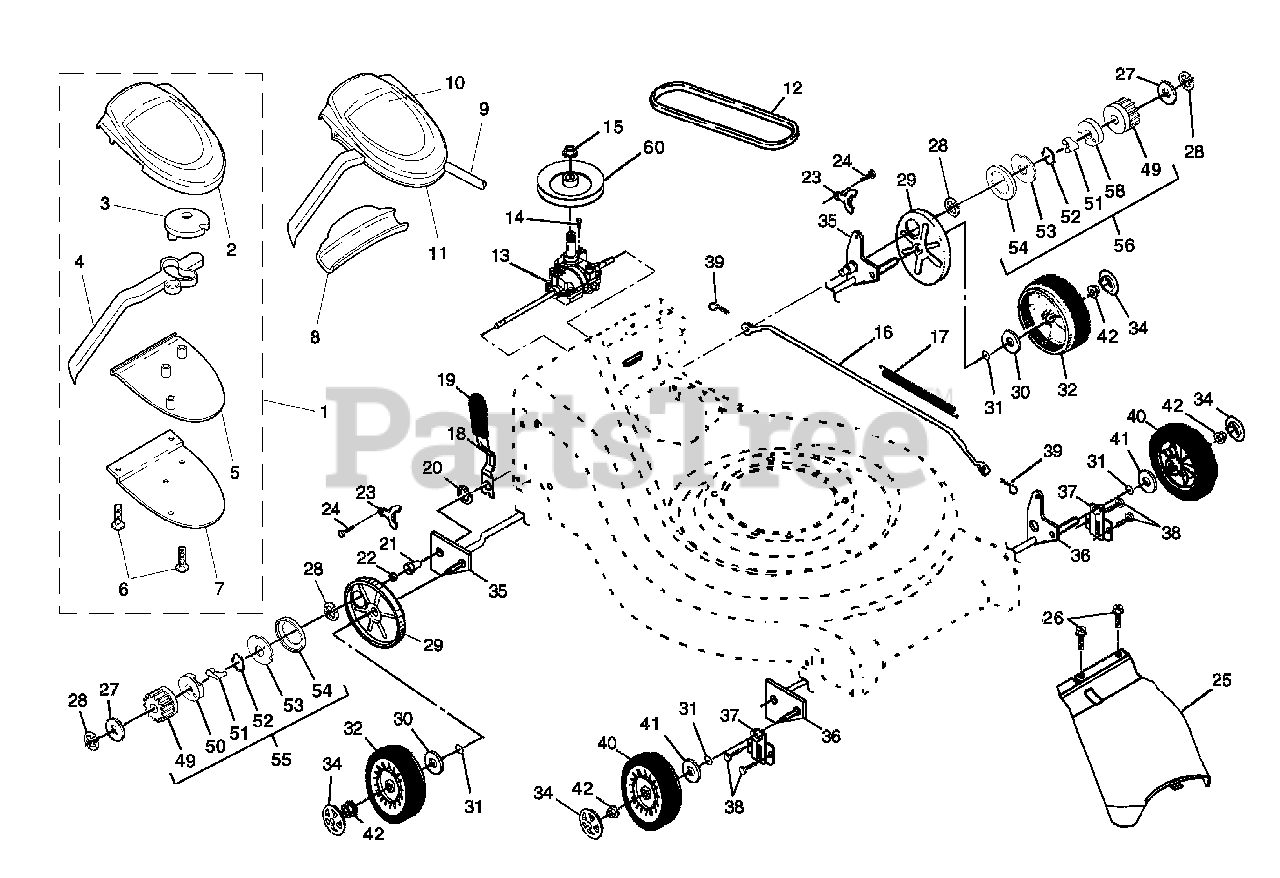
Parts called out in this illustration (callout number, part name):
1	Drive Control Assembly, Auto-Walk
2	Cover, Top, Auto-Walk Drive Control
4	Lever, Auto-Walk Drive Control
5	Cover, Bottom, Auto-Walk Drive Control
6	Screw, Phillips Head #10 x 5/8
7	Plate, Trigger, Auto-Walk Drive Control
8	Cap, Drive Control, Bottom
9	Cable, Drive Control
10	Decal, Drive Control
11	Decal, Drive Control Adjustment (bottom)
12	V-Belt
13	Gear Case Assembly
15	Nut, Hex, Flanglock, Zinc Plated 3/8-16
16	Rod, Connecting
17	Spring, Extension
18	Spring Selector
19	Knob, Selector Spring
21	Bearing, Support
22	Bearing, Ball
23	Retainer, Drive Assembly, Stamped
24	Screw, Tapping, Hex Head 1/4-20 x .75
25	Cover Drive
26	Screw, Threaded, Rolled #10-25 x .50
28	E-Ring 7/16
29	Cover, Dust, Wheel
30	Washer 1/2 x 1-1/2 x .134
31	O-Ring
32	Wheel 9 x 2
34	Hubcap
35	Shaft Assembly, Rear
36	Shaft Assembly, Front
37	Retainer, Front Shaft
38	Screw #12 x 5/8
39	Clip, Retainer
40	Wheel 8 x 2
41	Washer, Flat 3/8
42	Nut, Hex, Flangelock 3/8-16
49	Gear, Pinion
50	Retainer, Drive, RH
52	Spring, Torsion
53	Disc, Drive
54	Seal, Friction
55	Pinion Assembly, RH
56	Pinion Assembly, LH
58	Retainer, Drive, LH
60	Pulley, Drive
